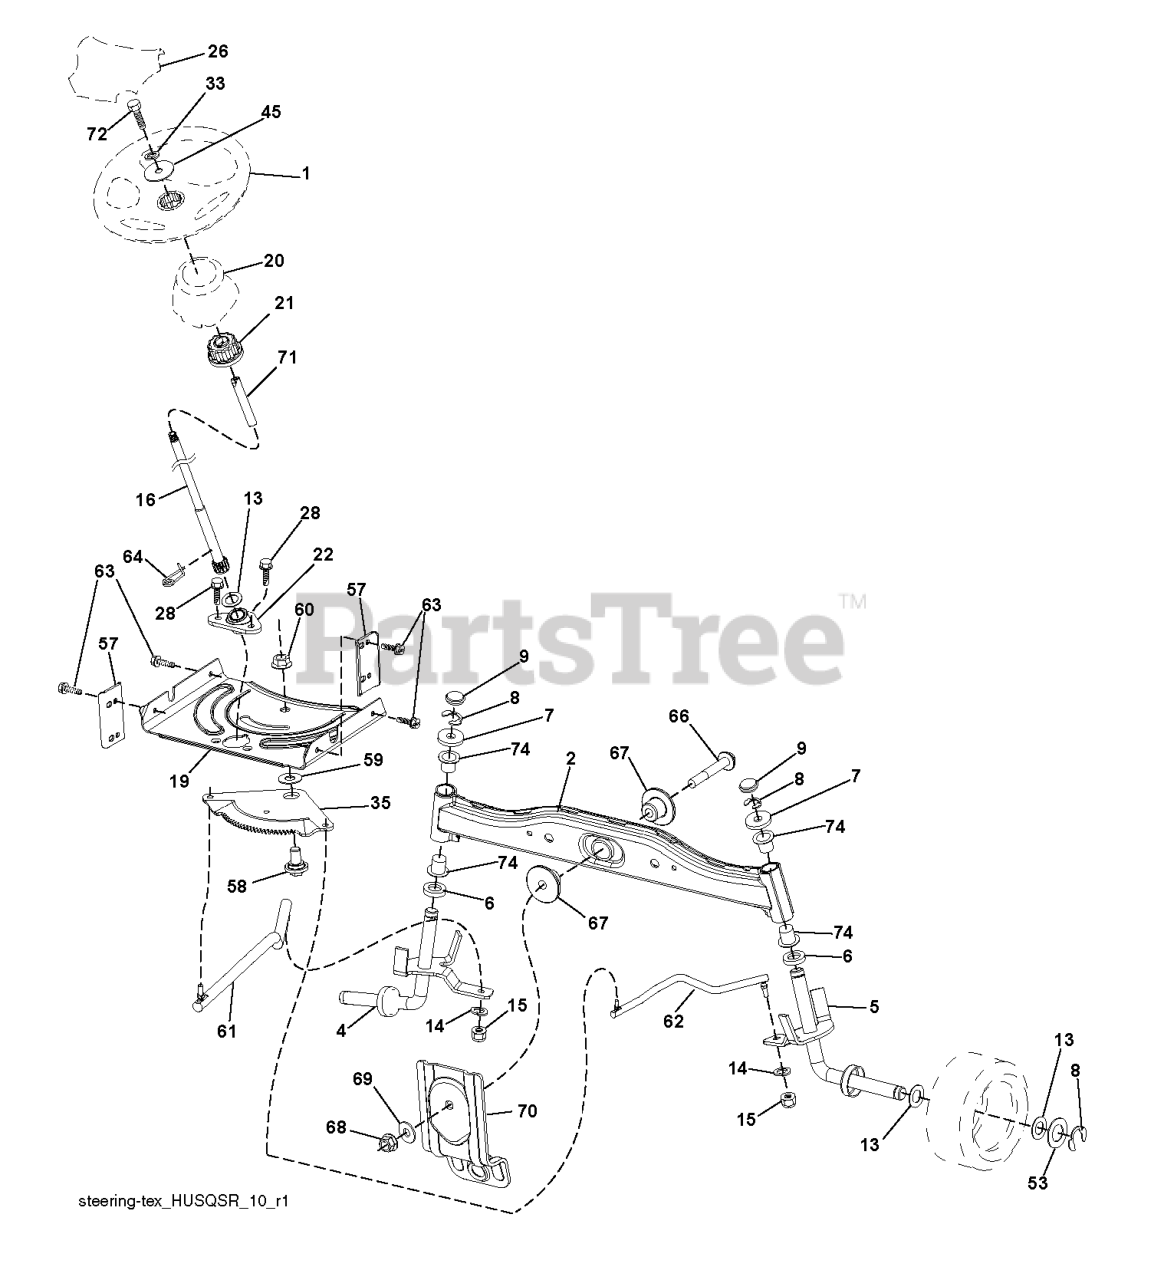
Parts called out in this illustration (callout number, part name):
1	RP WHEEL.STEER.HUSQ.PREM.OVMLD
2	AXLE HALF ASM-WELDED
4	SPINDLE.WELDED.LH.15"TEX
5	SPINDLE.WELDED.RH.15"T
6	THRUST WASHER
9	CAP.SPINDLE.BLACK
14	WASHER, LOCK 3/8
15	NUT CROWNLOCK 3/8-24
16	SHAFT.STEER.3/4.PLATED.TEX
19	PLATE.STEER.DDL.NLT/NG
20	BOOT, STEERING
21	ADAPTER, WHEEL STNG..
22	STEERING.SUPT.LOWER.
26	RP INSERT.CAP.WHL.STRG.HUSQ.
28	SCREW, 3/8-16X3/4
33	WASHER.LOCK.HVY.HLCL.SPR.5/16
35	GEAR.SECTOR.PLATE.DDL.
45	WASHER.11/32
53	WASHER.HARDENED
57	BRACKET.UPSTOP.TEX
58	BOLT.SHOULDER.SECTOR.P
59	WASHER.THURST.SECTOR.S
60	NUT FLANGE LOCK 5/8-11
61	DRAGLINK.LH.BALLSTUD.D
62	DRAGLINK.RH.BALLSTUD.D
63	SCREW
64	RETAINER.CLIP.SPRING.S
66	BOLT HEX FGHD 7/16-14 X 3 SERR
67	BUSHING.PM.FRONT AXLE
68	NUT.LOCK.FLANGE.7/16
69	WASHER.1.5X.505X.118
70	BRKT.DECK.SUSPENSION.F
71	SHAFT.EXTEN.STRG.SPLINE
72	BOLT 5/16-18 X 4 W/PATCH
74	BRNG T
